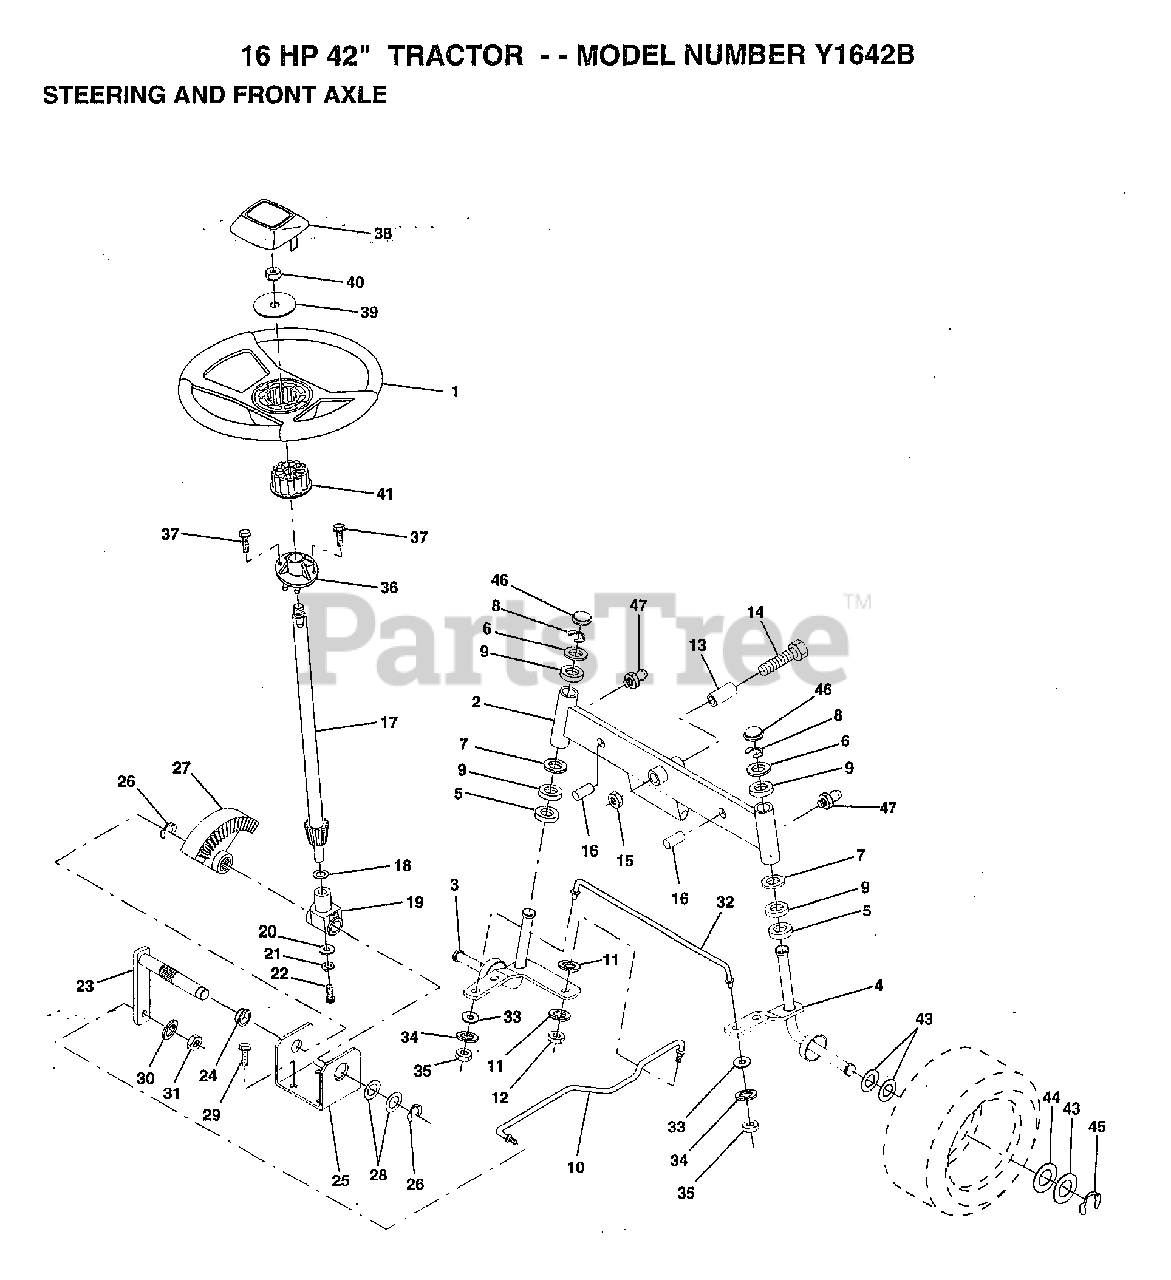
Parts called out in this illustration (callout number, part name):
3	SPINDLE LH
4	SPINDLE RH
5	WASHER .T
6	WASHER
7	WASHER
8	RING
9	COL. SRTG. BEAR.
11	LOCKWASHER
13	BEARING
14	BOLT HEX 5/8-11
15	"NUT-LOC,FLANGE LT"
16	AXLE PIN
17	STEERING SHAFT
18	THRUST WASHER
19	SUPPORT.SHAFT
21	LOCKWASHER
22	"SCREW,SPECIAL"
24	NYLINER T
25	"BRKT,STEERING"
26	RING
27	GEAR SECTOR
28	WASHER .T
29	SCREW
30	LOCKWASHER
32	TIE ROD
33	WASHER M
34	LOCKWASHER
35	NUT.LOCK.5/16-24
38	INSERT STEERING
39	WASHER
41	ADAPTER LT
43	WASHER
44	WASHER
45	RING
46	CAP
47	ZERK M
